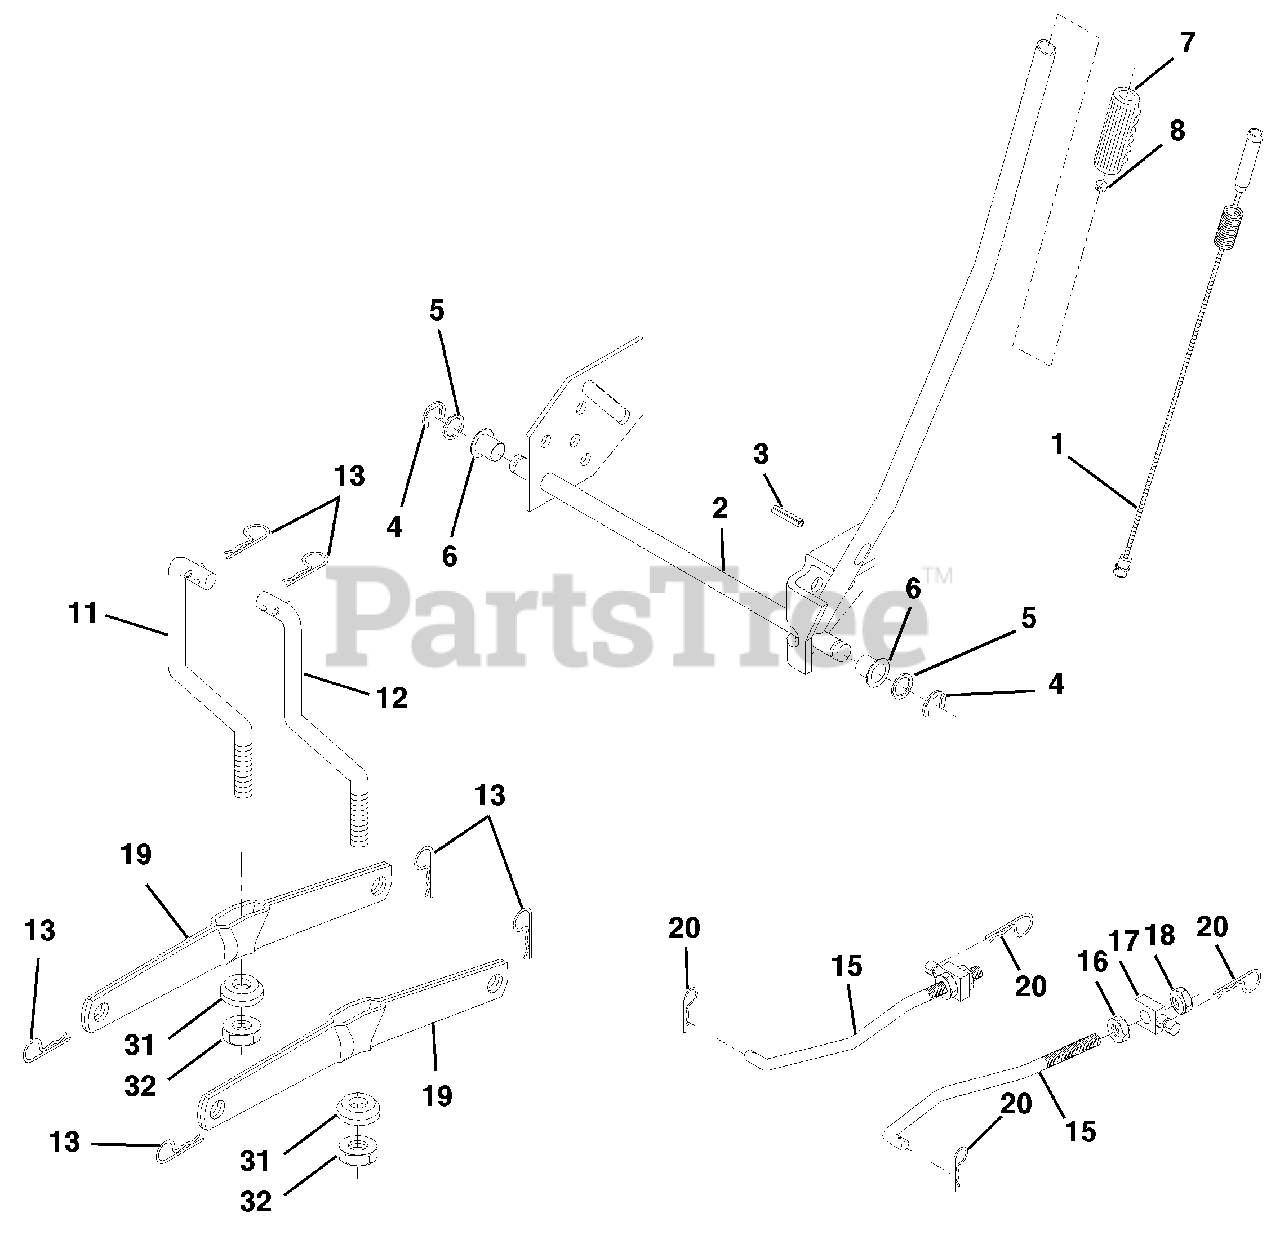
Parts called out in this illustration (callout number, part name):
1	Wire Asm Inner/Sprg w/Plngr Lt
2	Shaft Asm Lift
3	Pin Groove
4	E Ring #5133-62
5	Washer PLTD 21/32 X 1 X 21ga
6	Bearing Nylon Blk 629 Id
7	Grip Handle Bicycle
8	Button Plunger Black
11	Link Lift LH
12	Link Lift RH
13	Retainer Spring
15	Link Front
16	Nut Jam Hex 1/2-13 Unc
17	Trunnion Blk Zinc
18	Nut Lock W/wsh 1/2-13unc
19	Arm Suspension Rear
20	Spring, Retainer
31	Bearing Pvt. Lift Spherical
32	Nut Crownlock 3/8-24
